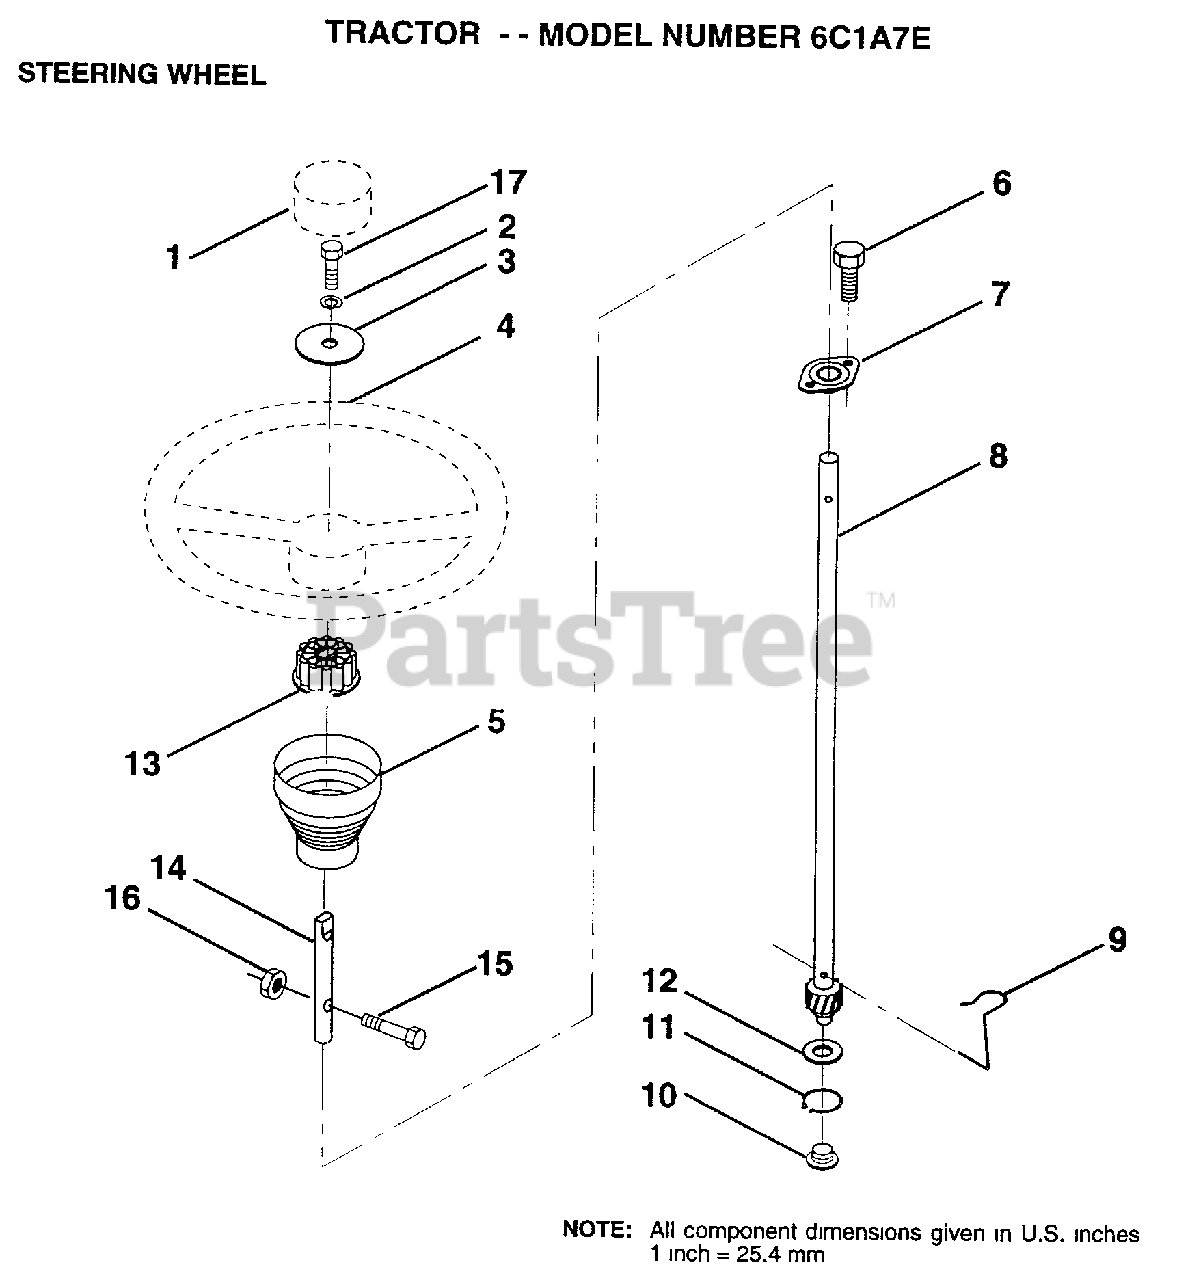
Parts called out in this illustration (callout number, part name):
1	ST WHL INSERT CAP
2	LOCKWASHER
3	WASHER T
5	SLEEVE STEERING
9	STEERING CLIP
10	BUSHING STEER LWR
11	RING
12	WASHER LT
13	ADAPTER LT
14	EXT SHAFT STEERIN
15	BOLT
16	NUT
17	BOLT
